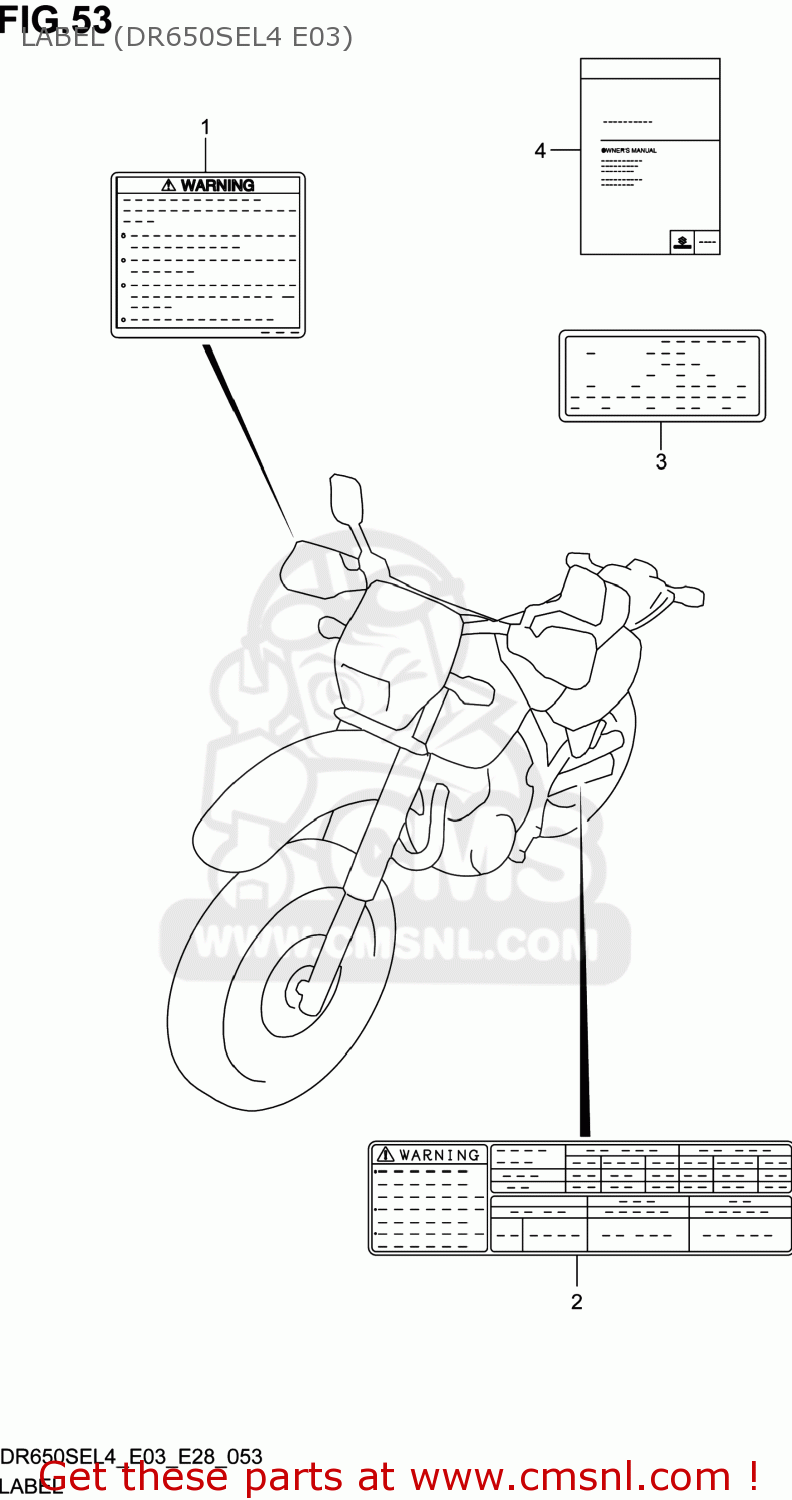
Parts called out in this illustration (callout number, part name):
1	LABEL,GENERAL WARNING
2	LABEL,TIRE INFORMATION
3	LABEL,MANUAL NOTICE
4	MANUAL,OWNER'S
